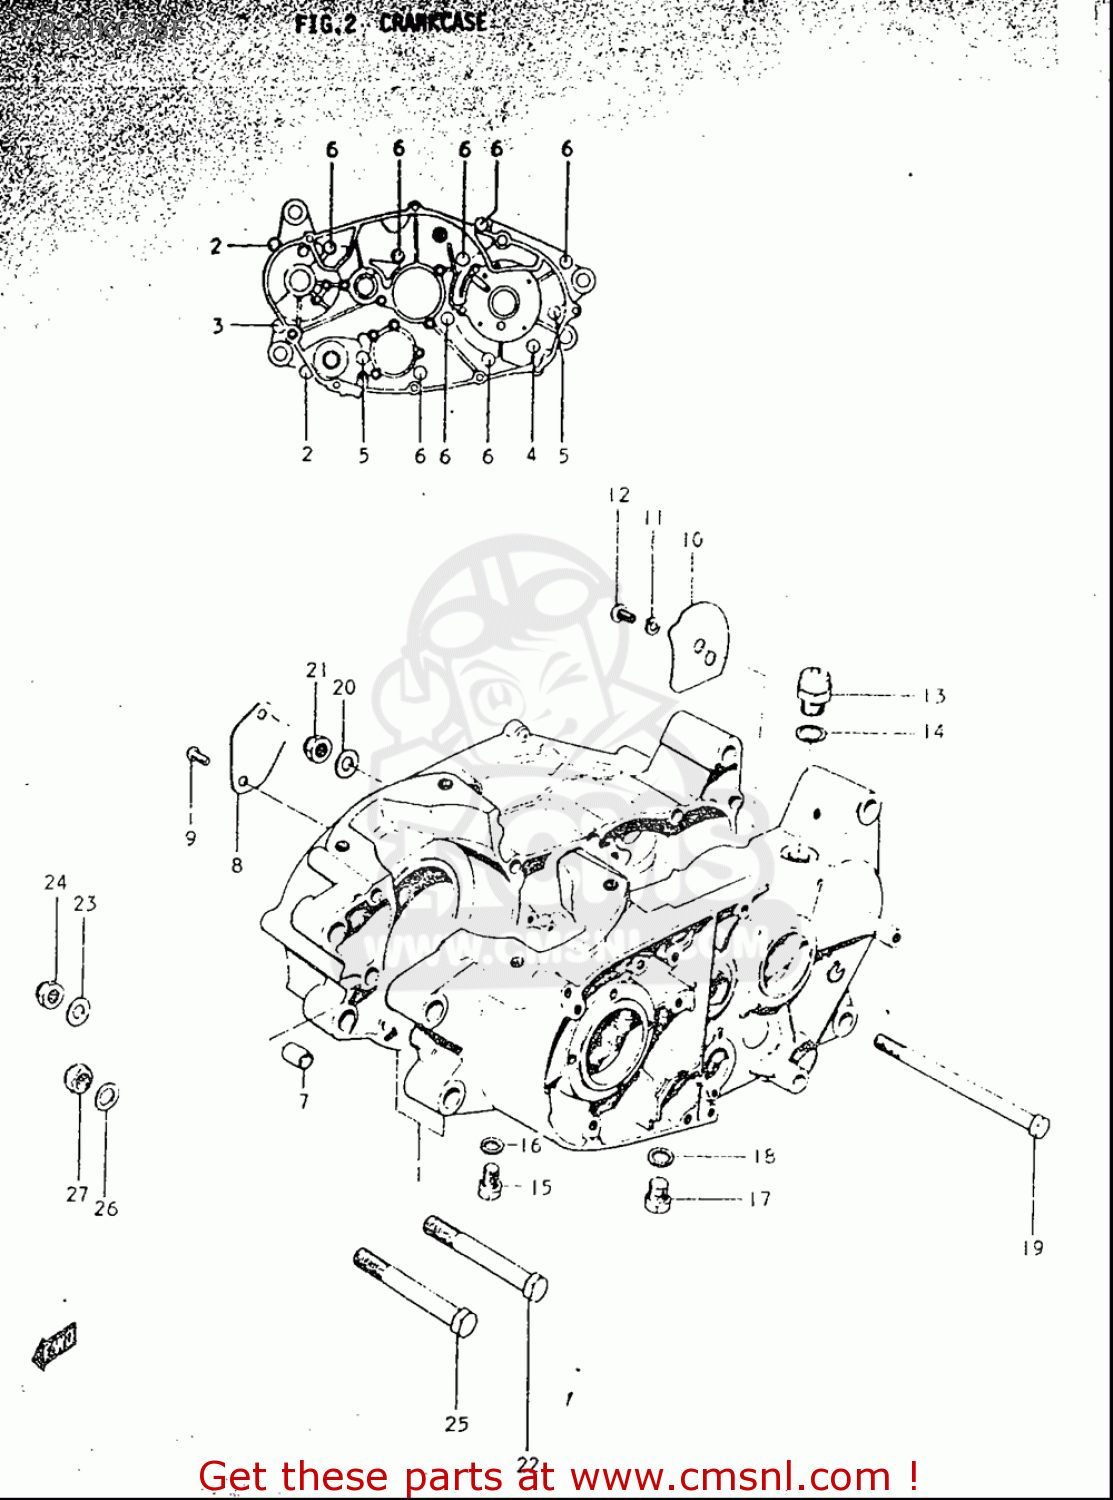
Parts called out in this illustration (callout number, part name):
2	SCREW
3	SCREW
4	SCREW
5	SCREW
6	SCREW
7	PIN
9	SCREW
11	WASHER,LOCK
14	GASKET(14X19.2X2) (NAS)
15	PLUG
16	GASKET(10X14X3.6) (NAS)
17	PLUG,12X9
18	GASKET(12X16X2) (NAS)
19	BOLT(10X125)
20	WASHER
22	BOLT
23	WASHER
25	BOLT
26	WASHER
27	NUT
